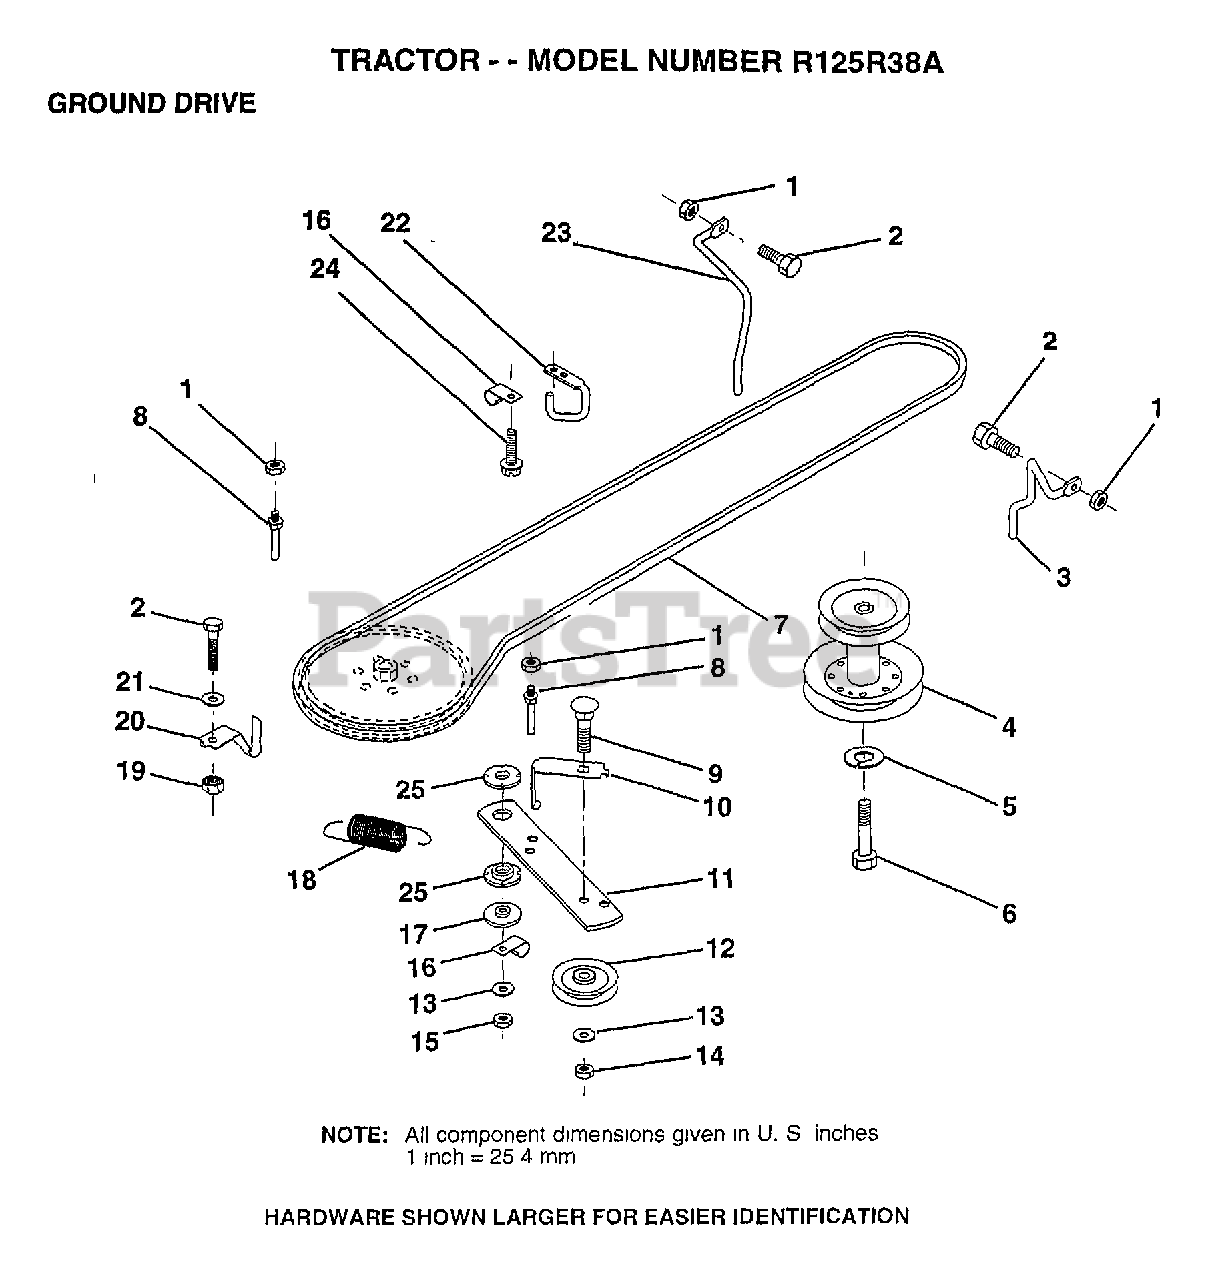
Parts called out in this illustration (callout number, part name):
2	BOLT
3	KEEPER.BELT.FRT.
4	PULLEY.ENGINE.LR
5	LOCKWASHER
6	HEX BOLT
7	V BELT
8	"KEEPER,DRIVE BELT"
9	BOLT
10	"KEEP,IDLER DR BEL"
11	ARM-IDLER.DR.GRND
12	IDLER, FLAT
13	WASHER
14	LOCKNUT
15	NUT
16	"CLIP,INSULATOR"
17	SPACER
20	KEEPER.BELT.T/A
21	WASHER
22	KEEPER, FRAME GROUND DRIVE BELT
23	KEEPER.BELT.LH.FR
24	SCREW
25	BUSHING.NYLON
